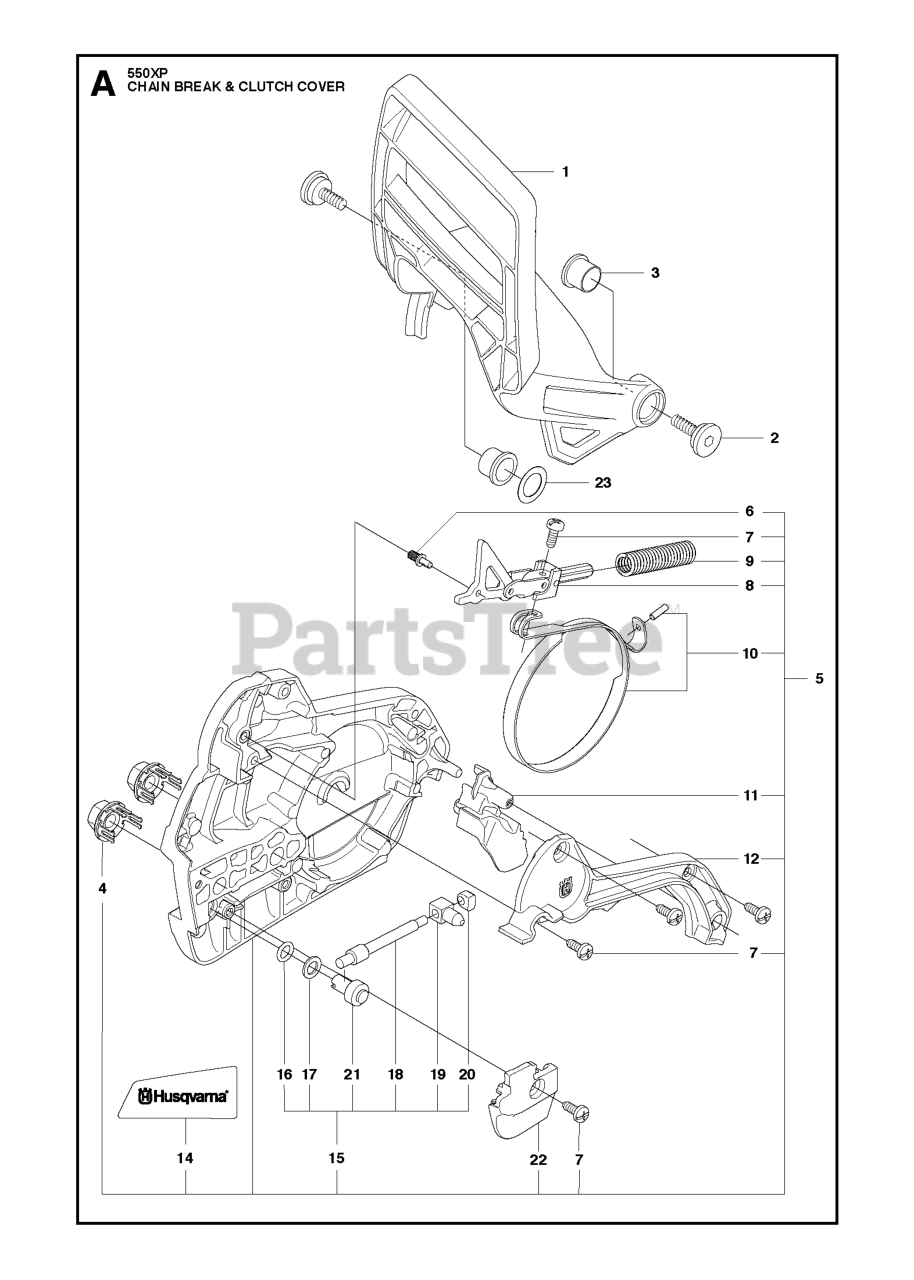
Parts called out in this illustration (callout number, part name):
1	HAND GUARD
4	NUT RETAINER ASSY
5	CLUTCH COVER
6	PIN
7	SCREW
8	KNEE JOINT ASSY
9	SPRING
10	BRAKE BAND ASSY
11	GUARD
12	COVER
14	LABEL
15	CHAIN TENSIONER KIT
16	O-RING
17	WASHER
18	WORM WHEEL
19	WORM SCREW
20	PAWL RIGHT HAND THREADED
21	SLEEVE
22	CHAIN GUIDE
23	WASHER STEEL
